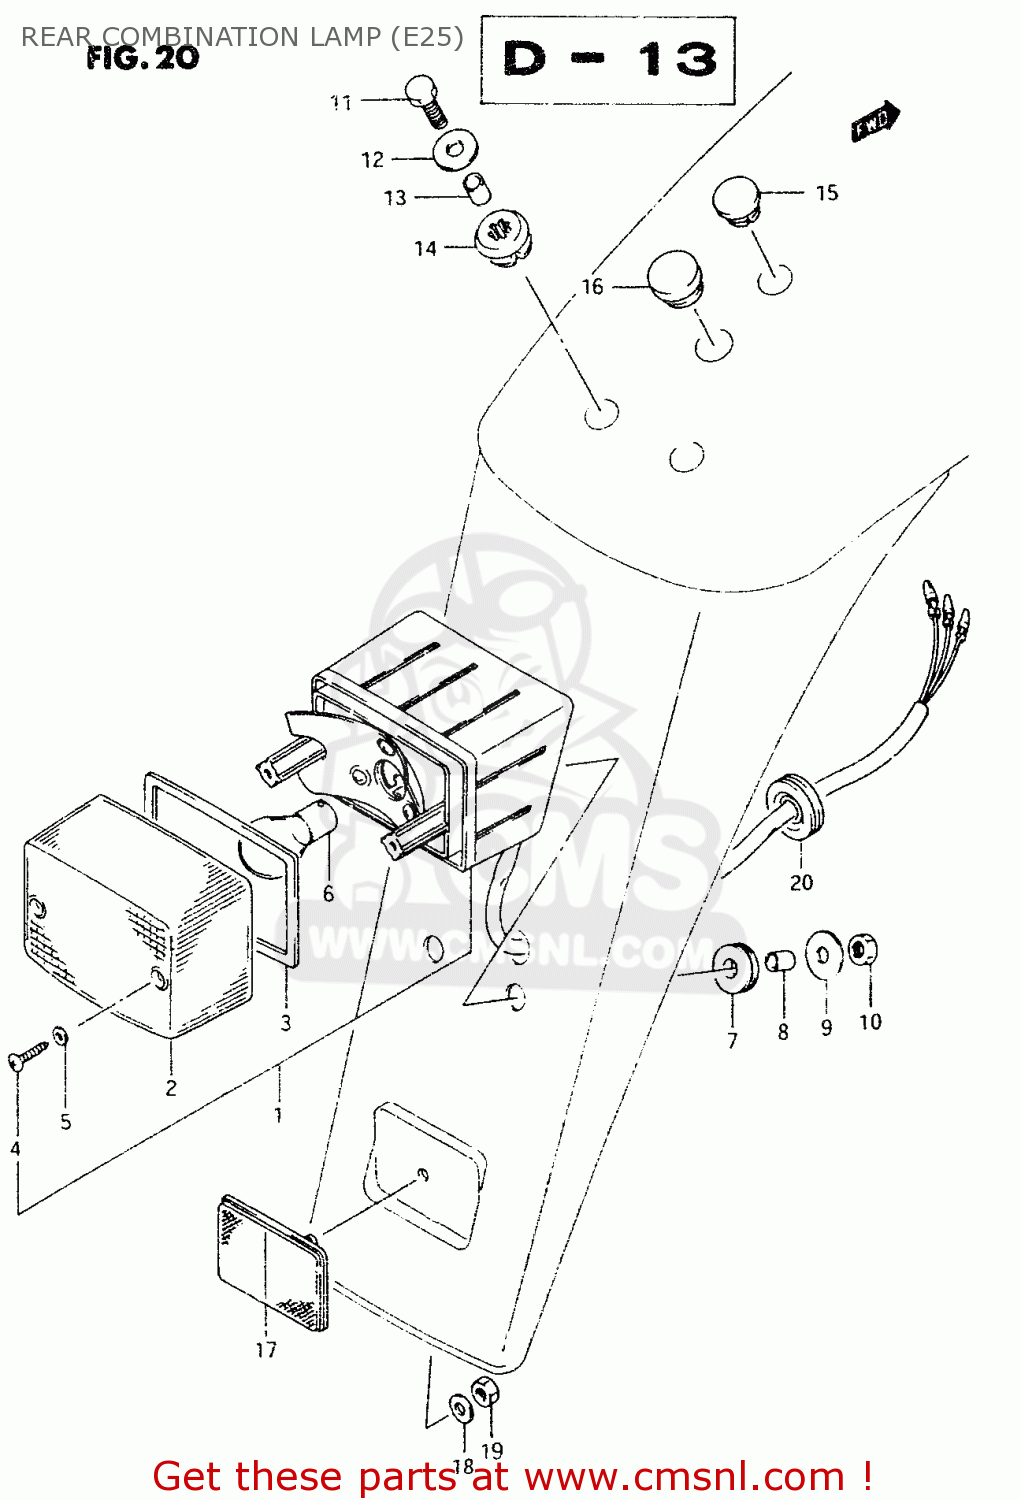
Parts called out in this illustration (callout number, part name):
1	LAMP ASSY, REAR COMBINATION
2	LENS
3	GASKET,RR COMBI LAMP LENS (NAS)
4	SCREW
5	GASKET (NAS)
6	BULB(12V21/5W)
7	CUSHION
8	SPACER
9	WASHER (6.5X22X1.6)
10	NUT
11	BOLT
12	WASHER (6.5X20X1.2)
13	SPACER (6.4X9X10.5)
14	CUSHION
15	PLUG(OD:19)
16	PLUG(OD:22)
17	REFLEX REFLECTOR,RR
18	WASHER
19	NUT
20	GROMMET
